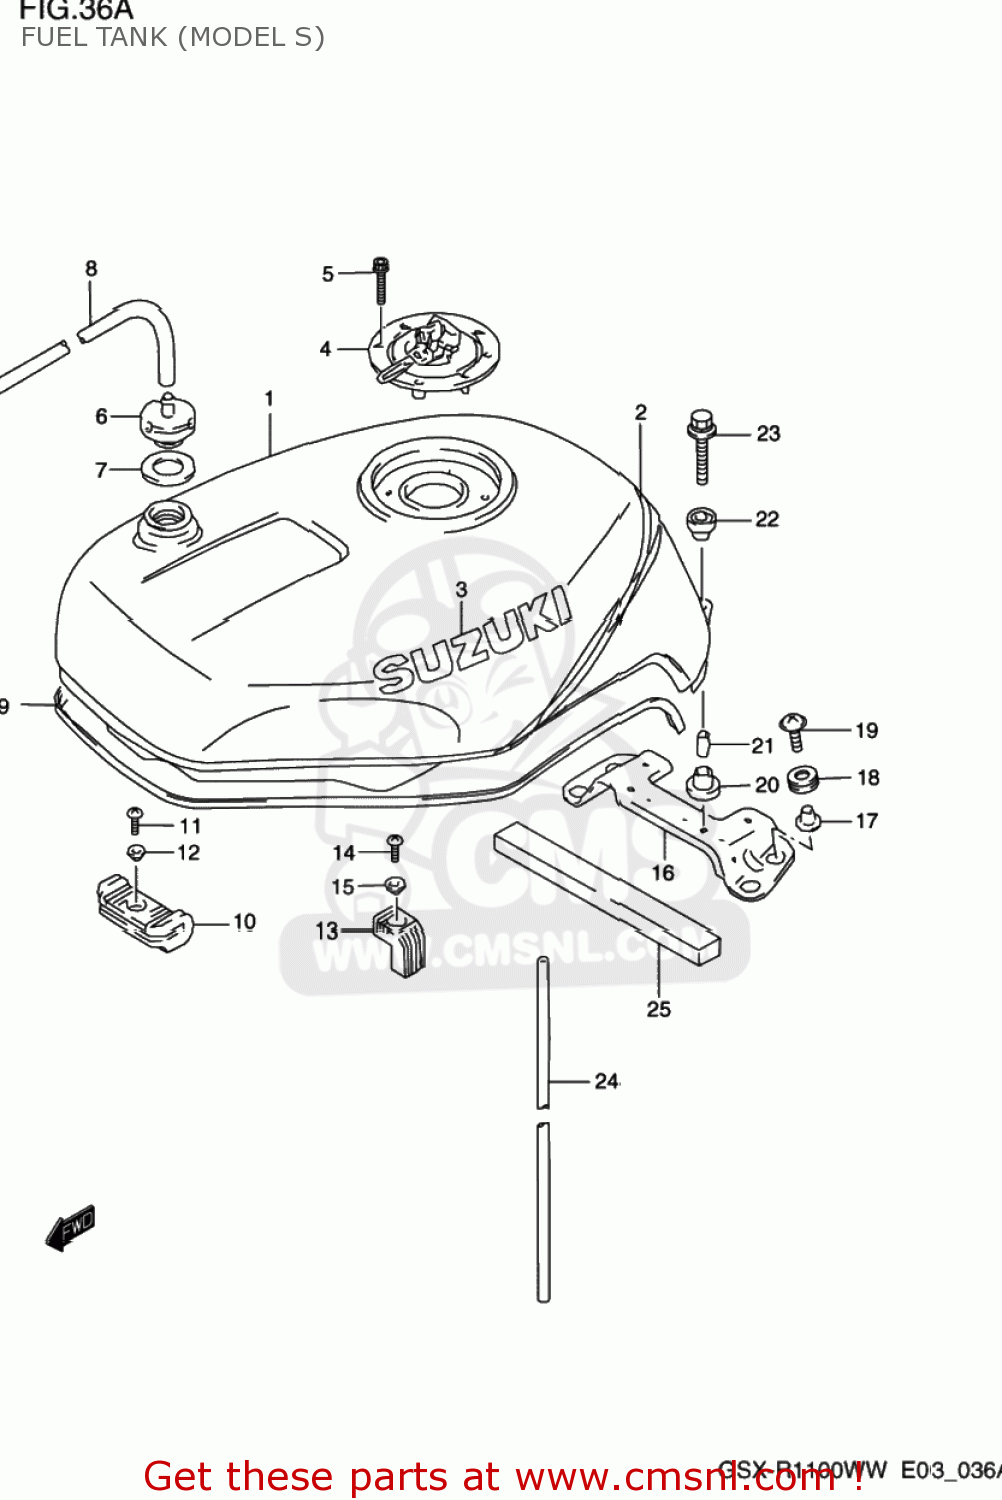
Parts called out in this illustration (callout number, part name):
1	TANK ASSEMBLY,FUEL
2	TAPE,FUEL TANK STRIPE
3	EMBLEM,FUEL TANK
4	CAP SET,FUEL TANK
5	BOLT(5X20)
6	PLUG,FUEL TANK BREATHER
7	GASKET 27X40X2.5 (NAS)
8	HOSE(5X8.2X600)
9	MOLDING
10	CUSHION,FUEL TANK FR
11	SCREW
12	WASHER
13	CUSHION,TANK SIDE
14	SCREW
15	WASHER
16	BRACKET,FUEL TANK RR
17	WASHER
18	CUSHION
19	SCREW(6X25)
20	CUSHION
21	SPACER
22	CUSHION
23	BOLT
24	HOSE(7X10.2X2000)
25	CUSHION,AIR SEAL
